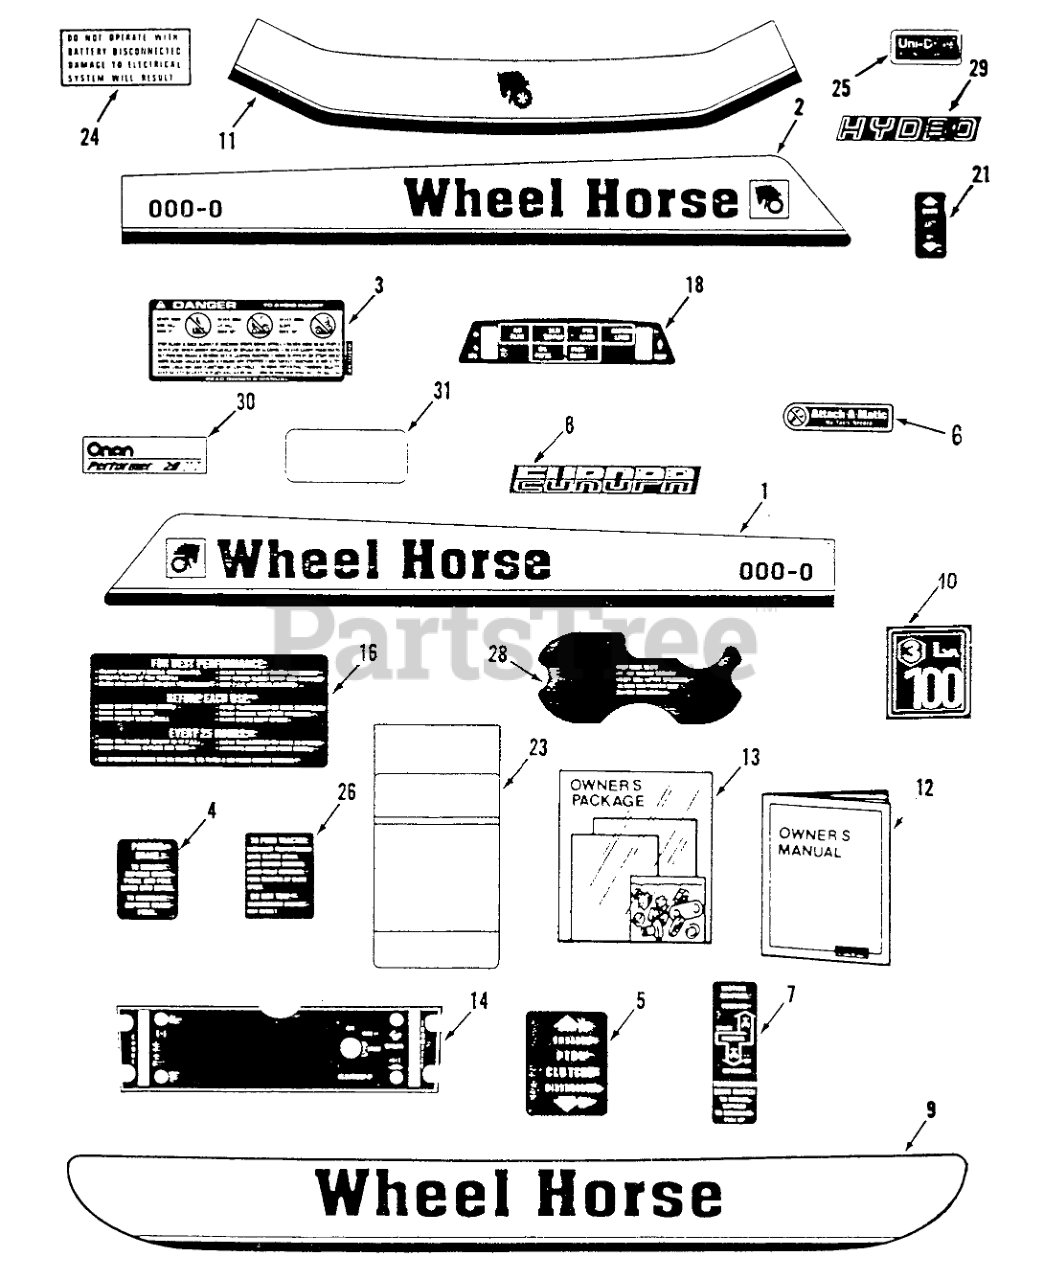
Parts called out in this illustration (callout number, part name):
1	DECAL-HOOD 518-H R H
2	DECAL-HOOD 518-H L H
3	DECAL-DANGER
4	DECAL-PARKING, BRAKE
5	DECAL PTO CLUTCH
6	Decal-Attac-O-Matic
7	DECAL-MOTION CONTROL
8	DECAL-EUROPA
9	DECAL-FENDER
10	DECAL-EUROPE
11	DECAL-FRONT HOOD
12	Owners Manual-Tractor
14	DECAL-FRONT PANEL
16	DECAL-REAR HOOD
18	DECAL-INDICATOR LTS
21	DECAL-LIFT
23	MAINTENANCE-DECAL
24	DECAL ELECT SYSTEM
25	Decal-Unidrive
26	DECAL-TO PUSH TRACT
28	DECAL-SEAT LIFTER
29	DECAL-HYDRO
30	Decal-Performer 16 HP (vendor #98-5640-02)
31	DECAL-OVERLAY
